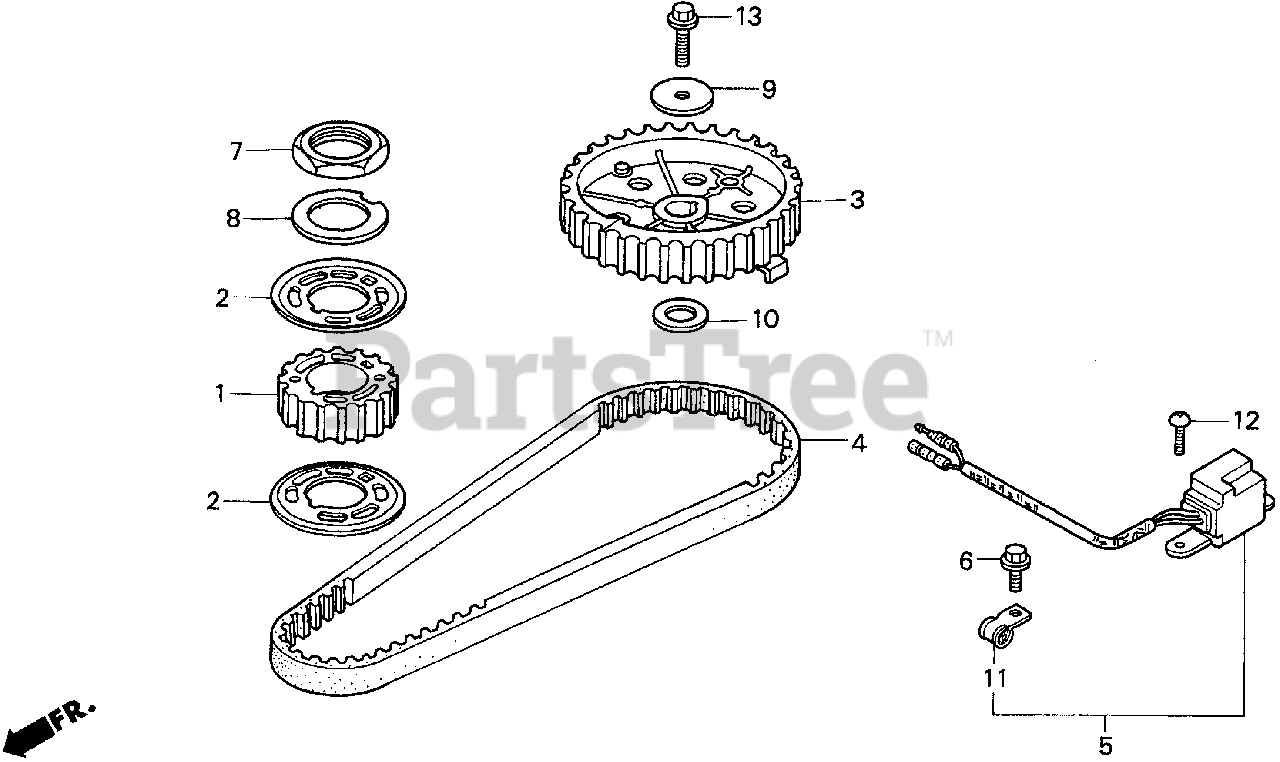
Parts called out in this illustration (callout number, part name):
1	PULLEY, TIMING
2	FLANGE, TIMING PULLEY
3	PULLEY, CAM
4	BELT, TIMING
5	COIL ASSY., PULSER
6	BOLT, FLANGE (6X12)
7	NUT, CAP (6MM)
8	WASHER, LOCK (27MM)
9	WASHER, PLAIN (6MM)
10	WASHER, PLAIN (13MM)
11	CLIP, CORD
12	SCREW, PAN (5X14)
13	BOLT, FLANGE (6X18)
